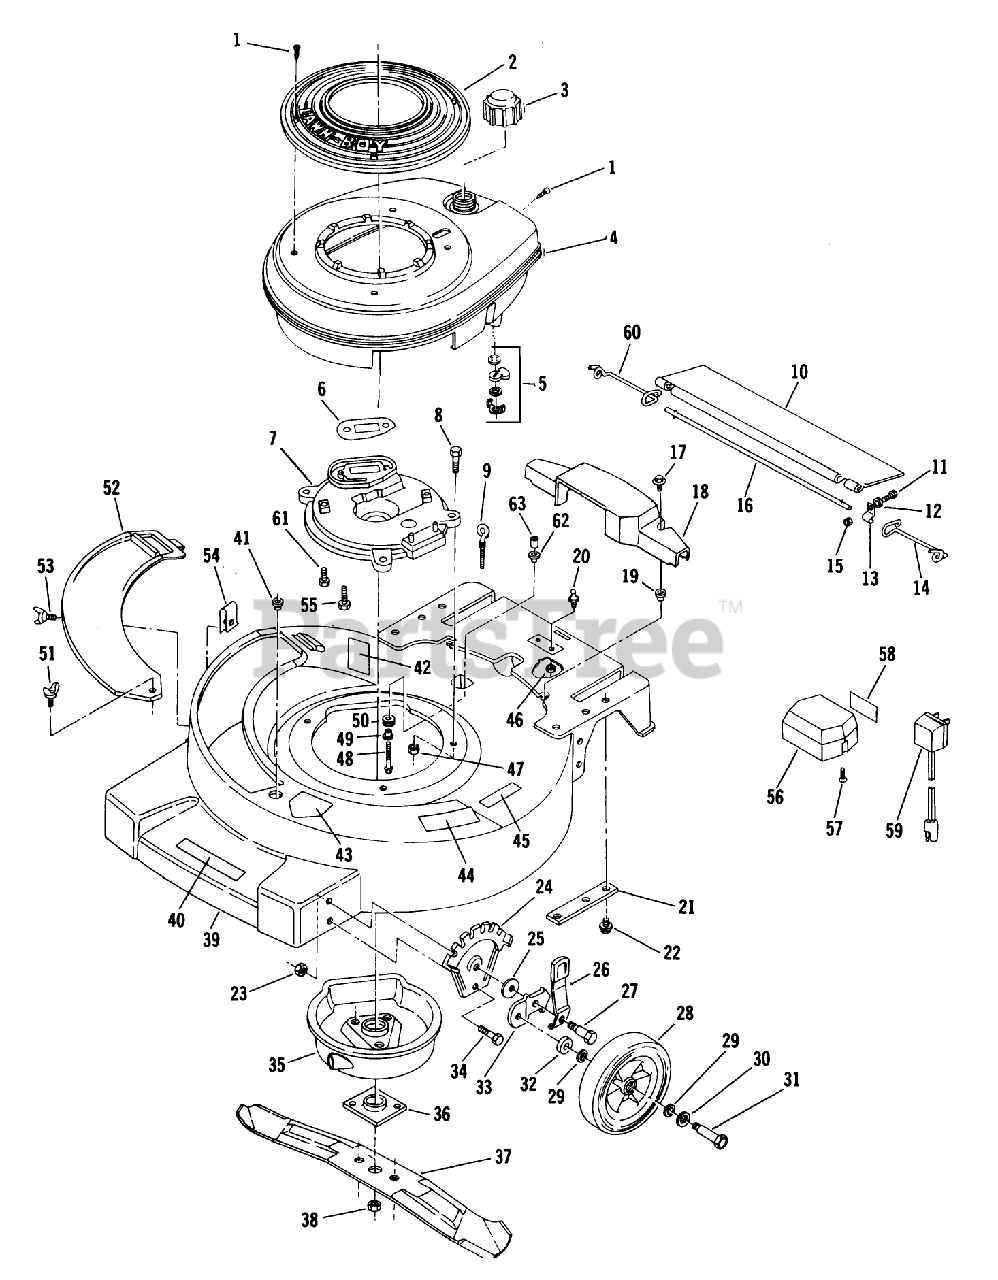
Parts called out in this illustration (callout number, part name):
1	SCREW - SELF TAPPING
3	FUEL CAP & INSERT
5	SHUT OFF VALVE KIT
7	PLATE,MUFFLER F
8	SCREW
9	EYE BOLT WAS MFG
10	SHIELD
12	WASHER F
13	CLAMP ROD KMC
14	SPRIG T/SHLD ASOC
15	LOCKNUT E
17	SCREW SEMS TRM HEX HD
22	SCREW
23	LOCKNUT
25	WASHER
29	WASHER
30	SPACER
31	BOLT WHEEL
32	WASHER WROUGHT
38	NUT-BLADE
44	PAD FOOT
47	NUT-LOCK F
49	SPACER ECK PRES
51	WING SCREW LAWRE
52	PLATE
55	SCREW V
60	SPRING;TRAILING SHIELD RH
62	SPACER ECK PRES
63	SPACER
